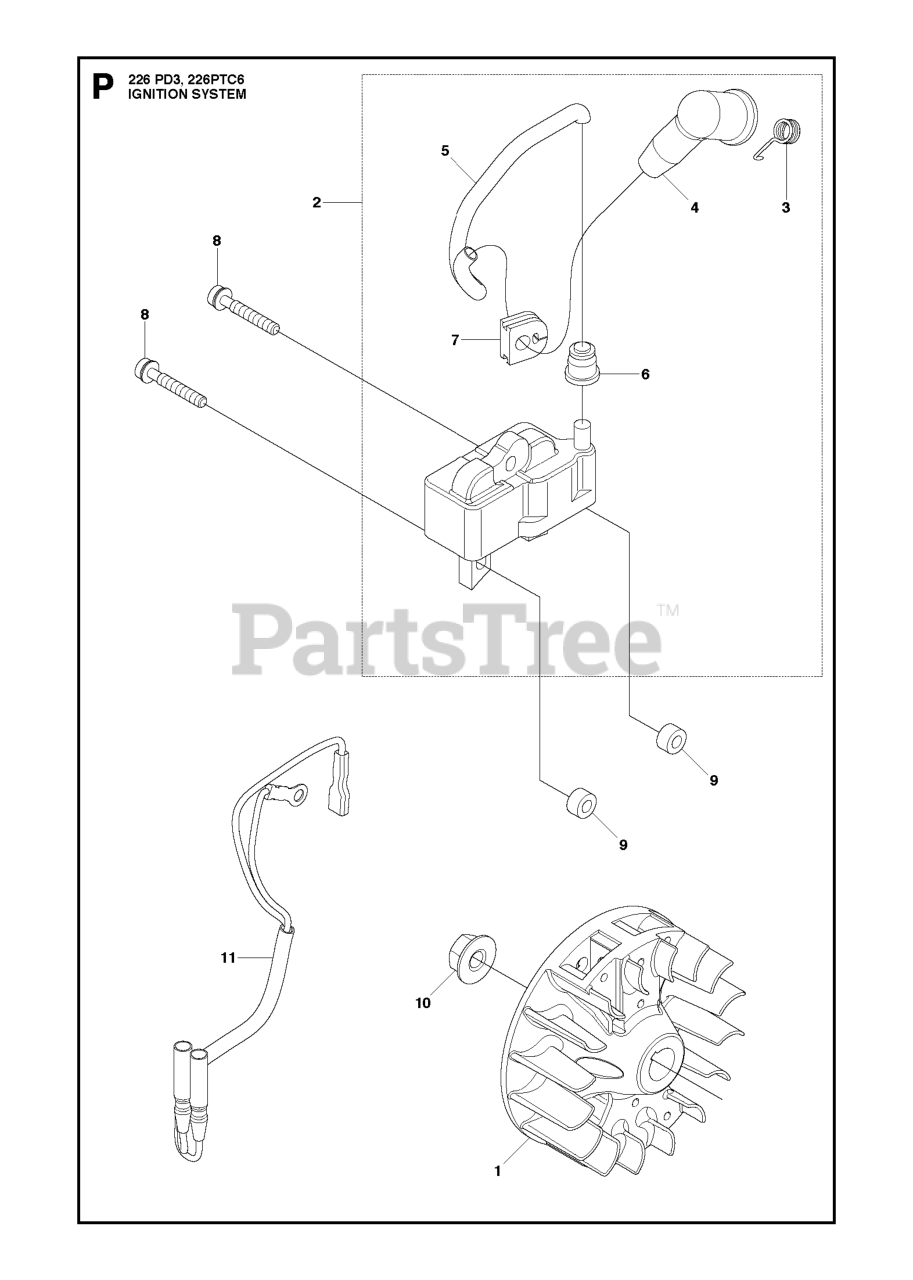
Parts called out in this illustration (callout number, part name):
6	CAP
7	GROMMET
9	SPACER
10	NUT
